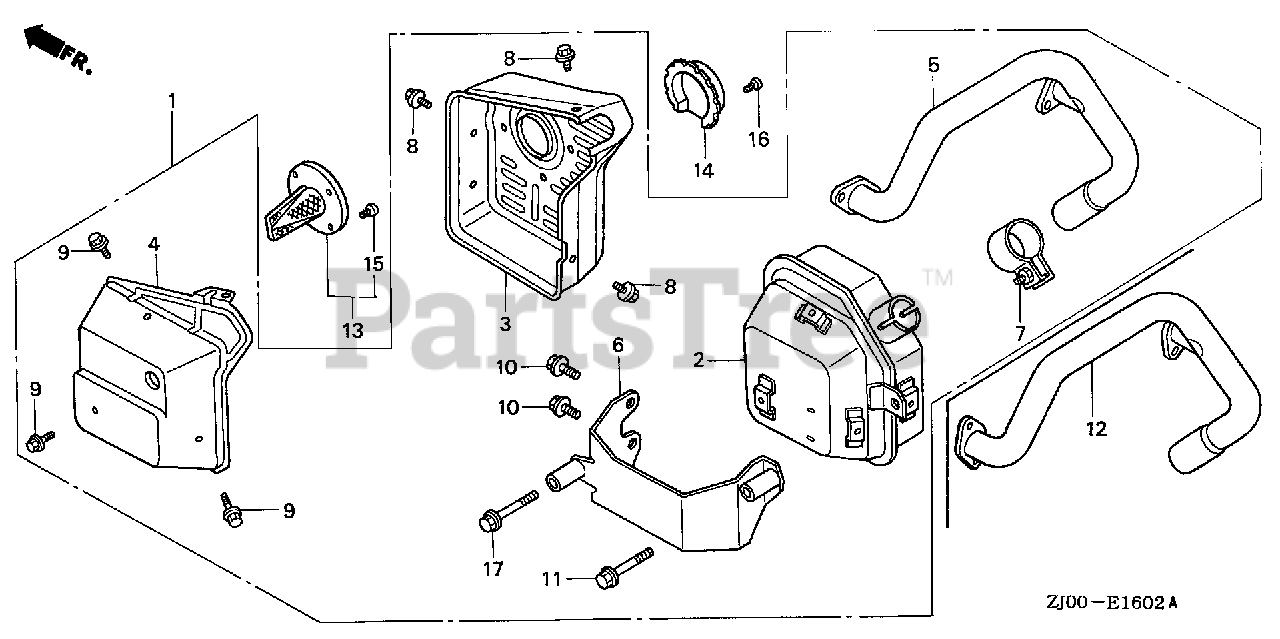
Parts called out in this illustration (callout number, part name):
2	MUFFLER COMP. (SIDE-L) (FUTABA) (SILVER MUFFLER)
3	PROTECTOR, MUFFLER (SIDE-L)
4	PROTECTOR, RR. MUFFLER (SIDE-L)
6	STAY, MUFFLER (SIDE-L)
7	BAND ASSY. (NOT AVAILABLE)
8	BOLT, FLANGE (6X8)
9	BOLT, FLANGE (6X8)
10	BOLT, FLANGE (8X14)
11	BOLT, FLANGE (6X50)
12	PIPE, EX. (SIDE-L)
13	ARRESTER, SPARK
14	DEFLECTOR KIT, EX.
15	SCREW (NELSON)
16	SCREW, TAPPING (4X8)
17	BOLT, FLANGE (8X50)
